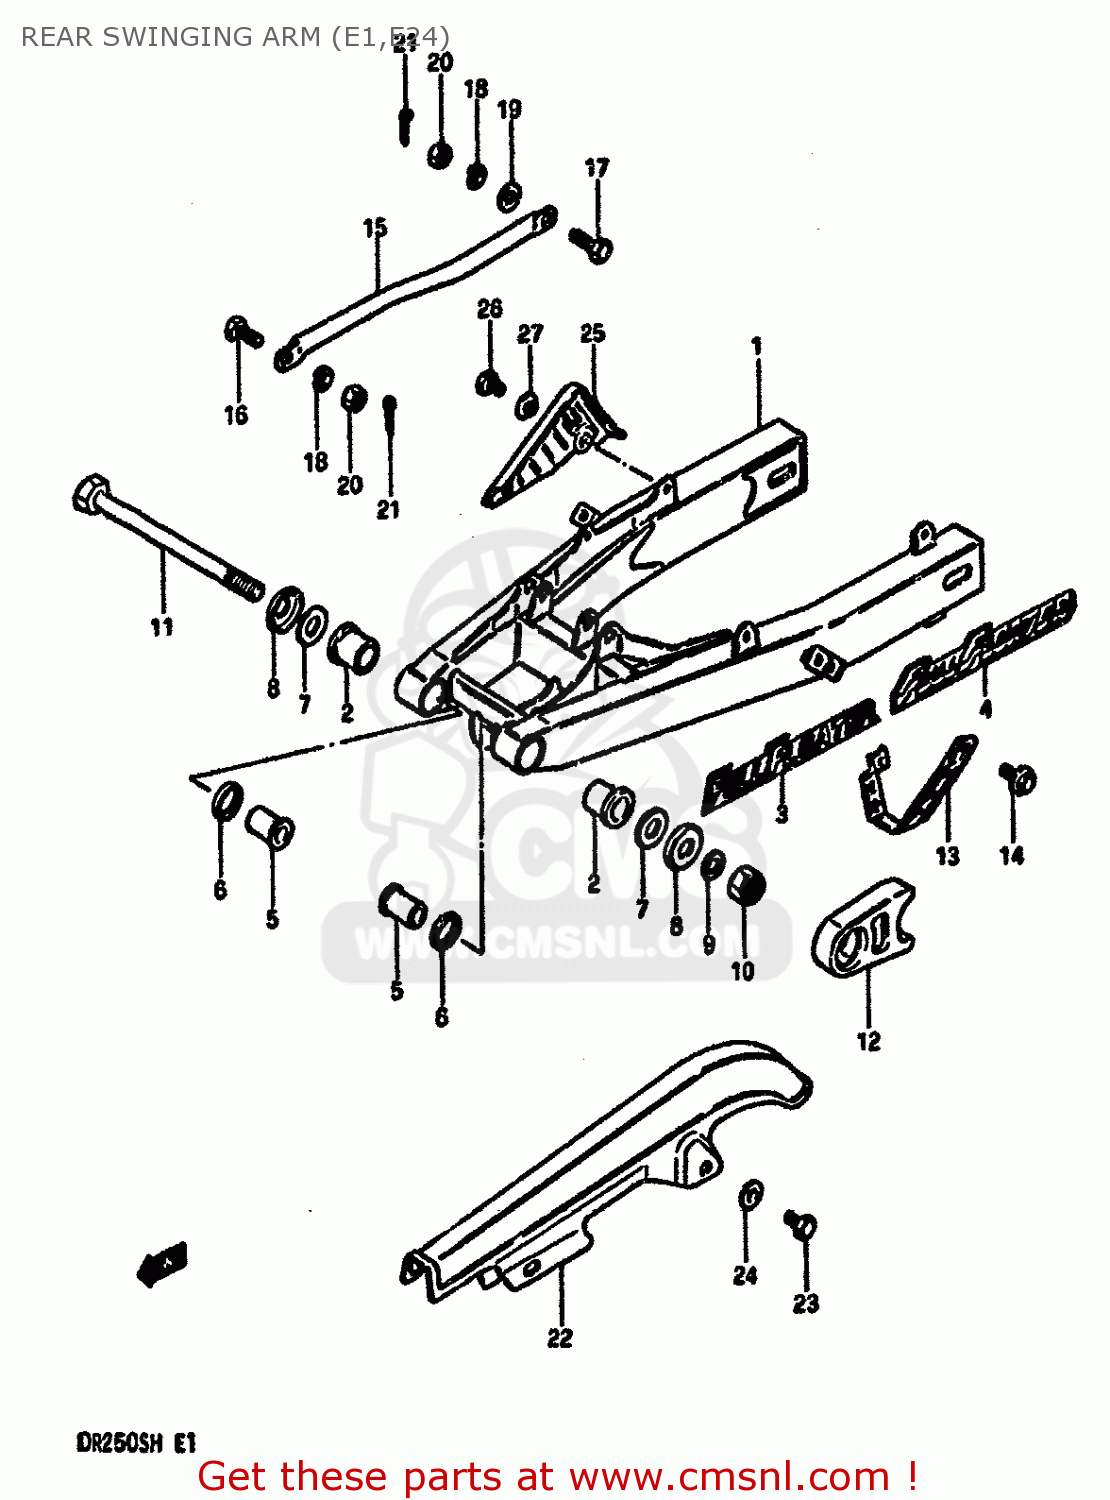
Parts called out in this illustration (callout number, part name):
1	SWINGING ARM,REAR (GOLD)
2	BUSHING,RR SWGARM PIVOT
3	EMBLEM,SWING ARM
4	MODEL G/H
5	SPACER,RR SWGARM PIVOT OUTER
6	SEAL,OIL(20X27X5)
7	WASHER
8	COVER,REAR SWING ARM DUST
9	WASHER
10	NUT 14MM
11	SHAFT,REAR SWING ARM
12	BUFFER,CHAIN TOUCH DEFLECTOR
13	GUIDE,DRIVE CHAIN
14	BOLT
15	LINK,REAR TORQUE
16	BOLT(8X22.5)
17	BOLT(8X26.5)
18	LOCK WASHER
19	WASHER
20	NUT
21	PIN 20X20
22	CASE,CHAIN
23	BOLT 6X8
24	WASHER
25	GUARD,PILLION FOOT
26	BOLT 6X8
27	WASHER
